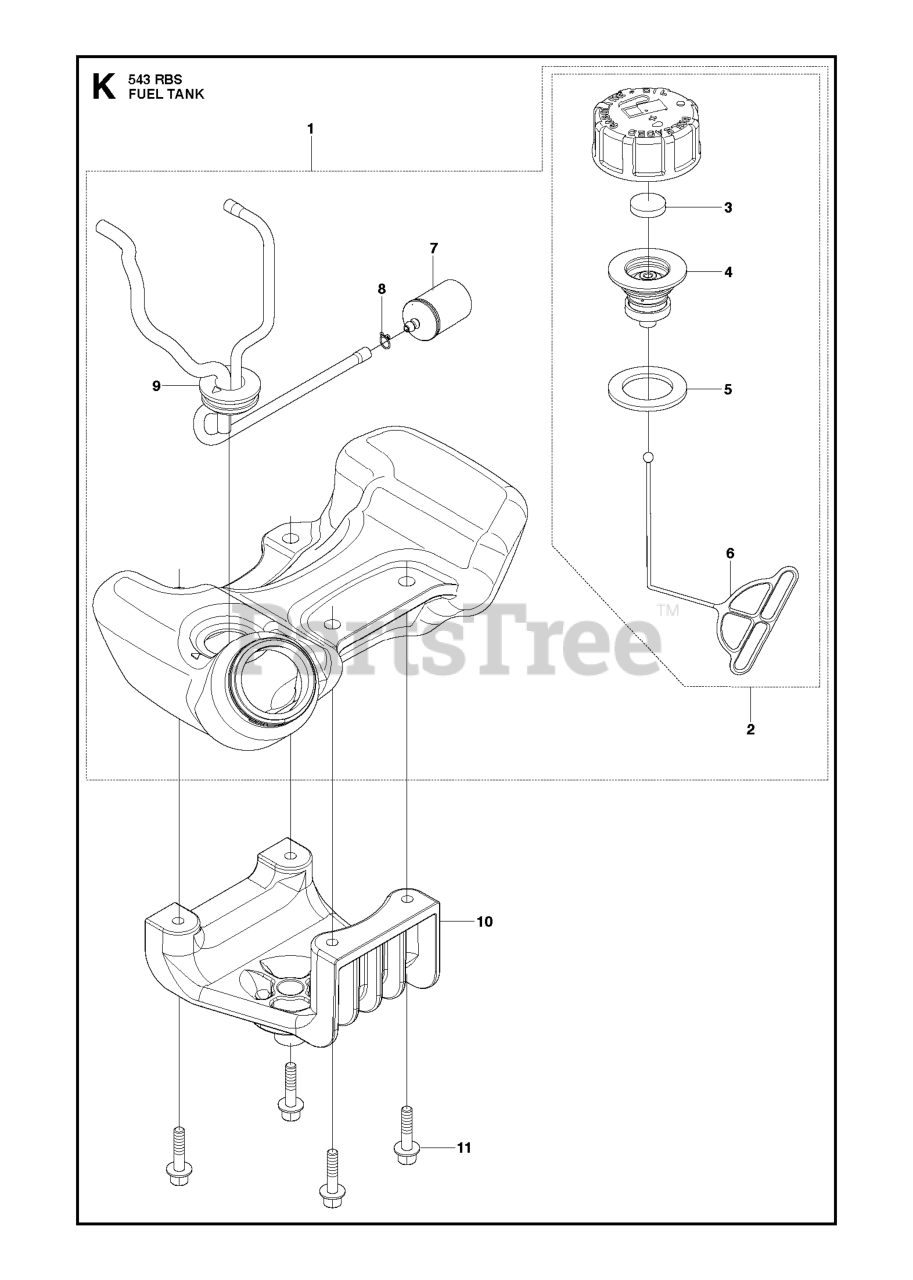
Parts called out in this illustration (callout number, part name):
2	ASSY FUEL CAP
7	RP FUEL FILTER
11	BOLT M5X25
